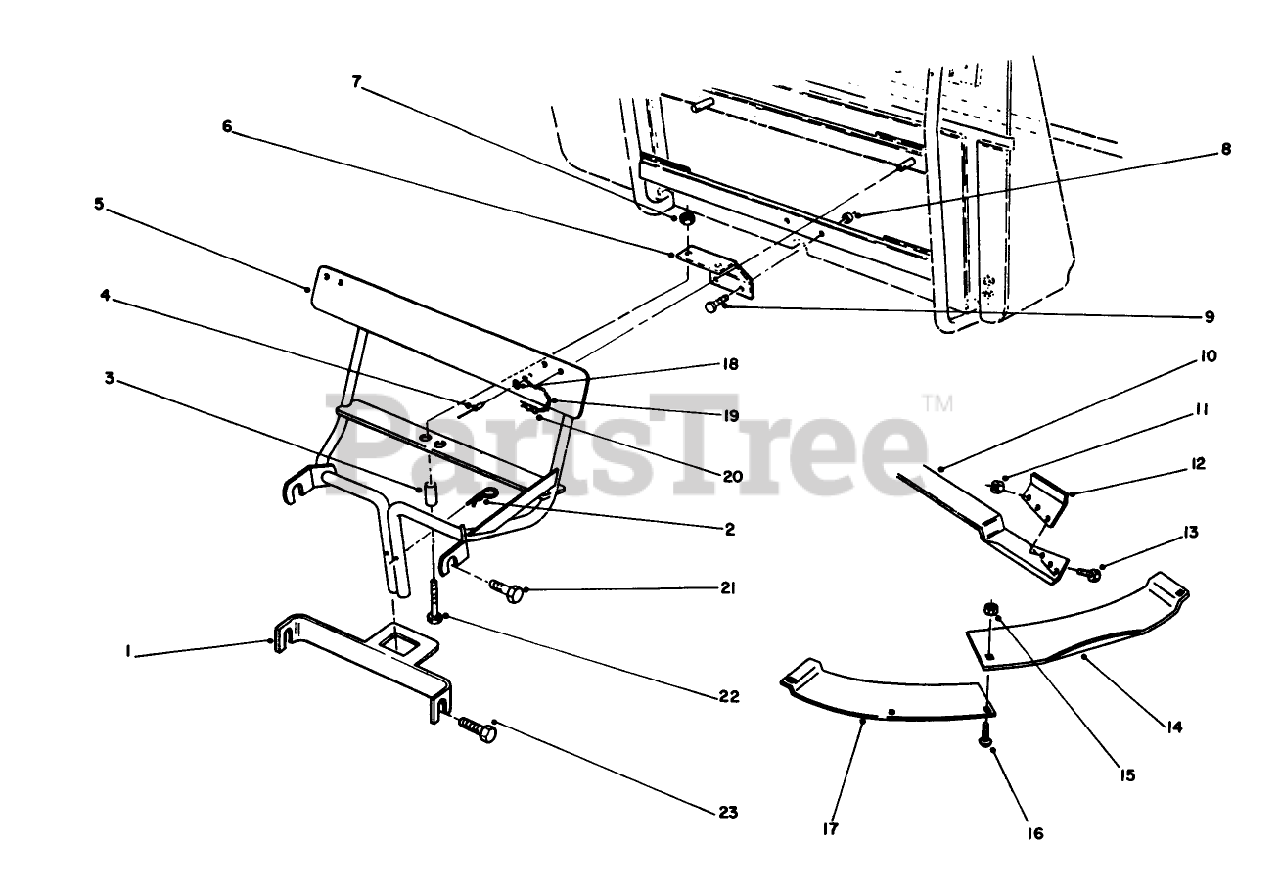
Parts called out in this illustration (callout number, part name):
1	Bracket-Support
2	Hairpin
3	Spacer
4	Rivet-Pop
5	WLDMT-QUICK ATTAC B
6	Bracket-Hitch
7	NUT-LOCK, NI
8	NUT-LOCK, NI
9	SCREW-HH
10	Blade (Ref.)
11	NUT-LOCK 5/16-18
12	Kit-Lift Tab, 30" Only (Incl. Ref. #11 & 13)
13	BOLT 5/16-18X5/8
14	PLATE MOWER B
15	NUT-LOCK, NI
16	Bolt
17	PLATE MOWER RING B (NS)
18	WASHER
19	CHAIN MAKE FRM111098
20	Hairpin
21	SCREW-HH
22	Screw-Hex. Hd.
23	Bolt
